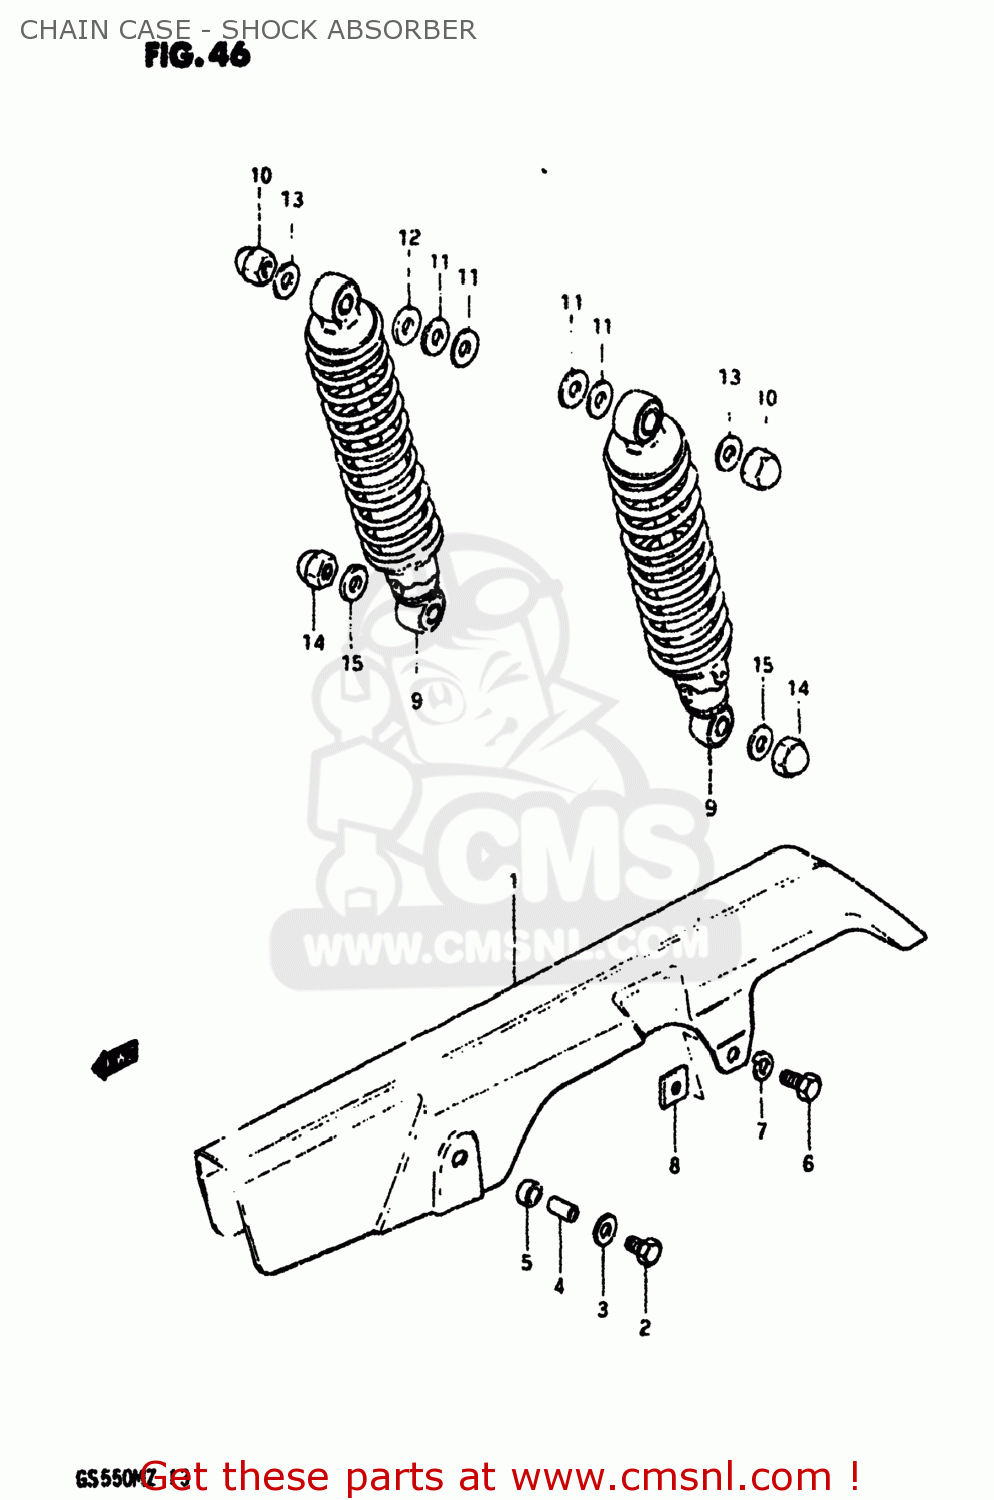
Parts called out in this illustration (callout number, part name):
1	CASE,CHAIN
2	BOLT
3	WASHER(6.5X18X1)
4	SPACER (6.1X8X5.2)
5	CUSHION
6	BOLT, UPPER
7	LOCK WASHER
8	NUT,CHAIN CASE RR
9	ABSORBER ASSEMBLY,REAR SHOCK
10	NUT
11	WASHER
12	WASHER (12.5X24X3.2)
13	WASHER
14	NUT, LOWER LH
15	WASHER
